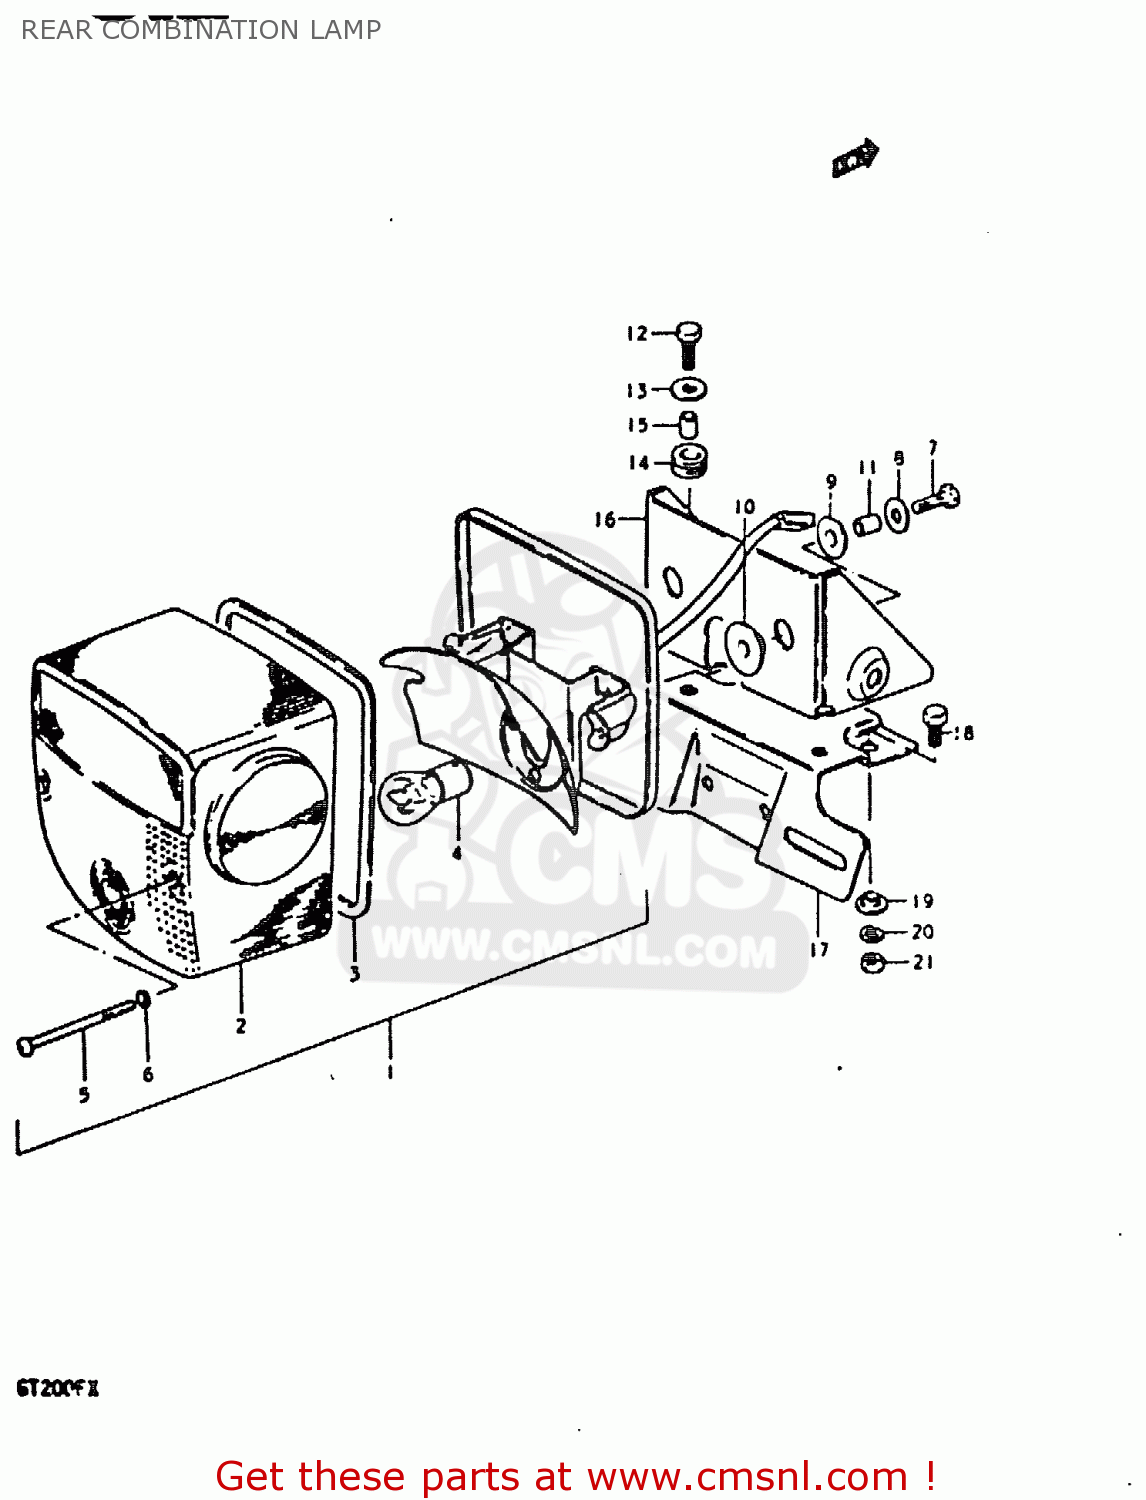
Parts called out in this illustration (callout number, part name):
1	LAMP ASSY, REAR COMBINATION
2	LENS
3	GASKET (NAS)
4	BULB(12V23W)
5	SCREW (4X55)
6	GASKET (NAS)
7	BOLT
8	WASHER (6.5X20X1.2)
9	CUSHION
10	CUSHION
11	SPACER (6.8X10X11.5)
12	BOLT, UPPER
13	WASHER (6.5X20X1.2)
14	CUSHION
15	SPACER (6.1X9X9)
16	BRACKET, COMBINATION LAMP
17	PLATE, LICENSE
18	BOLT
19	SPACER
20	LOCK WASHER
21	NUT
